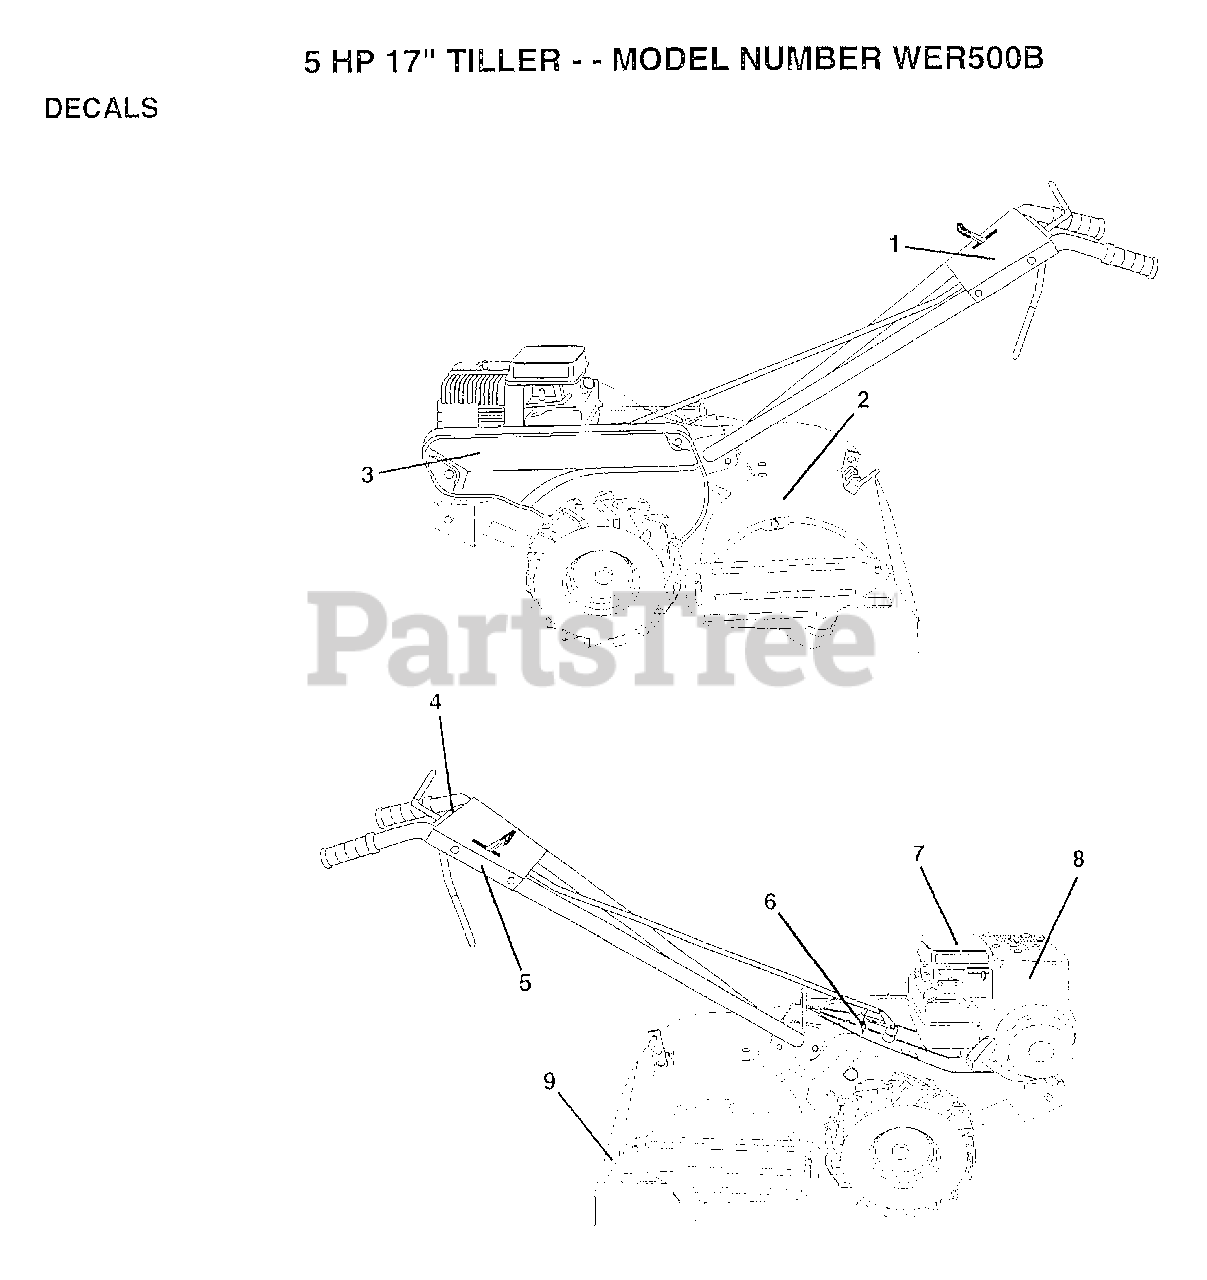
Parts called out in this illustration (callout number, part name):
1	DECAL PANEL CNTRL
2	DECAL SHIELD TINE
3	DECAL BELT GUARD
5	DECAL TI
7	DECAL TI
